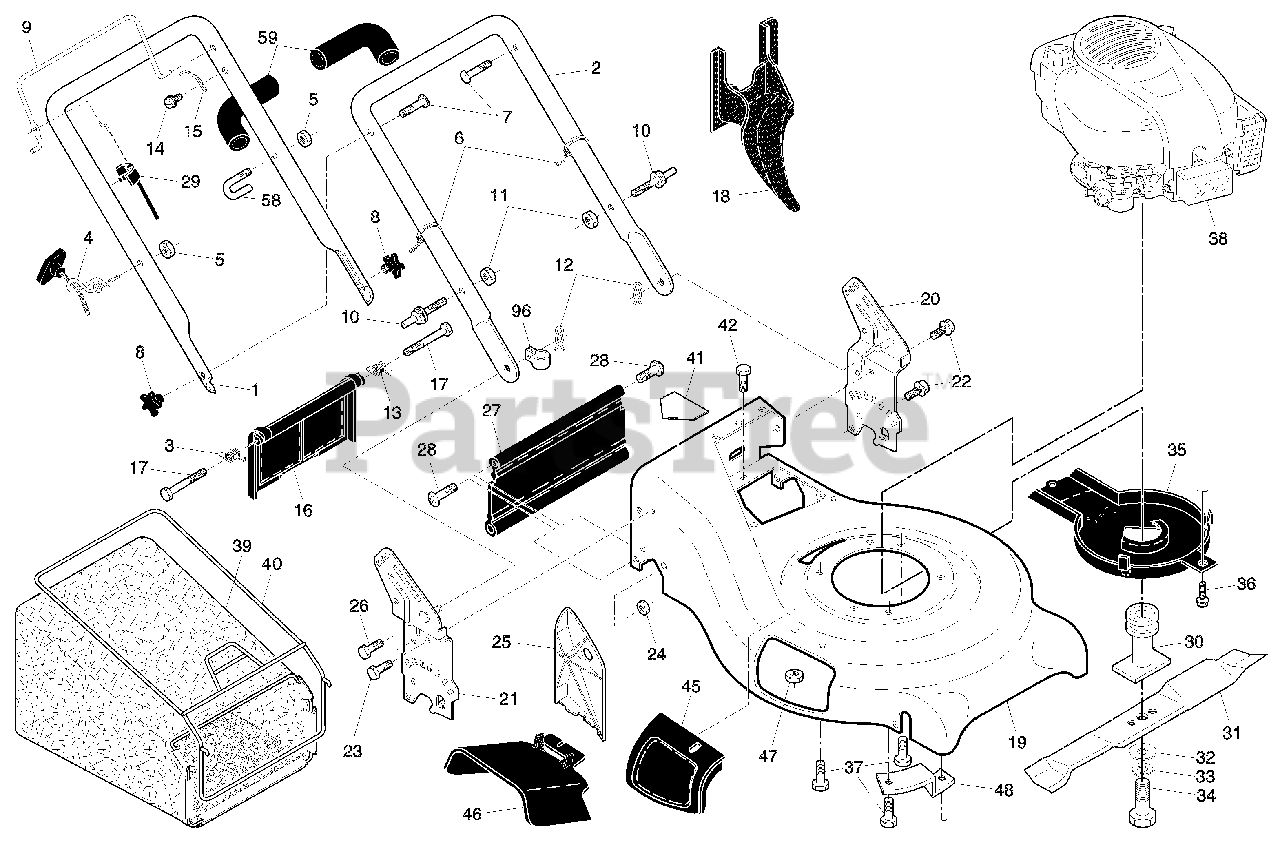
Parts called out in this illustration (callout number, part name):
1	Handle, Upper
2	Handle, Lower
3	Spring, Rear Door, RH
4	Guide, Rope, Side
5	Nut, Hex Lockwasher Insert 1/4-20
6	Wire, Tie
7	Bolt, Handle 5/16-18 x 1.75
8	Knob, Handle
9	Bail, Flat, Auto-Walk, Orange
10	Bolt, Carriage
11	Nut, Hex, Centerlock 5/16-18 UNC
12	Cotter, Hairpin
13	Spring, Rear Door, LH
15	Bracket, Upstop
16	Rear Door Assembly
17	Bolt, Rear Door
18	Plug, Mulcher
19	Kit, Lawn Mower Housing
20	Handle Bracket Assembly, LH
21	Handle Bracket Assembly, RH
22	Screw, Hex Washer Head
23	Bolt, Hex Head 5/16-18 x 5/8
24	Nut, Hex, with Lock Washer Insert 5/16-18
25	Baffle, Side
26	Screw, Hi-Lo Thread #12 x 5/8
27	Skirt, Rear
28	Screw, Hinge 1/4-20 x 1.25
29	Cable, Operator Presence
30	Blade Adapter / Pulley
31	Blade, 21"
32	Washer, Hardened
33	Lockwasher, Helical Spring 3/8
34	Screw, Hex Head 3/8-24 x 1.38
35	Debris Shield
37	Bolt, Engine
39	Grassbag
40	Frame, Grassbag
41	Danger Decal
45	Mulcher Door Assembly
46	Deflector, Discharge
48	Mounting Bracket, Debris Shield
59	Grip, Handle, Foam, Smooth
96	Clip, Cable
